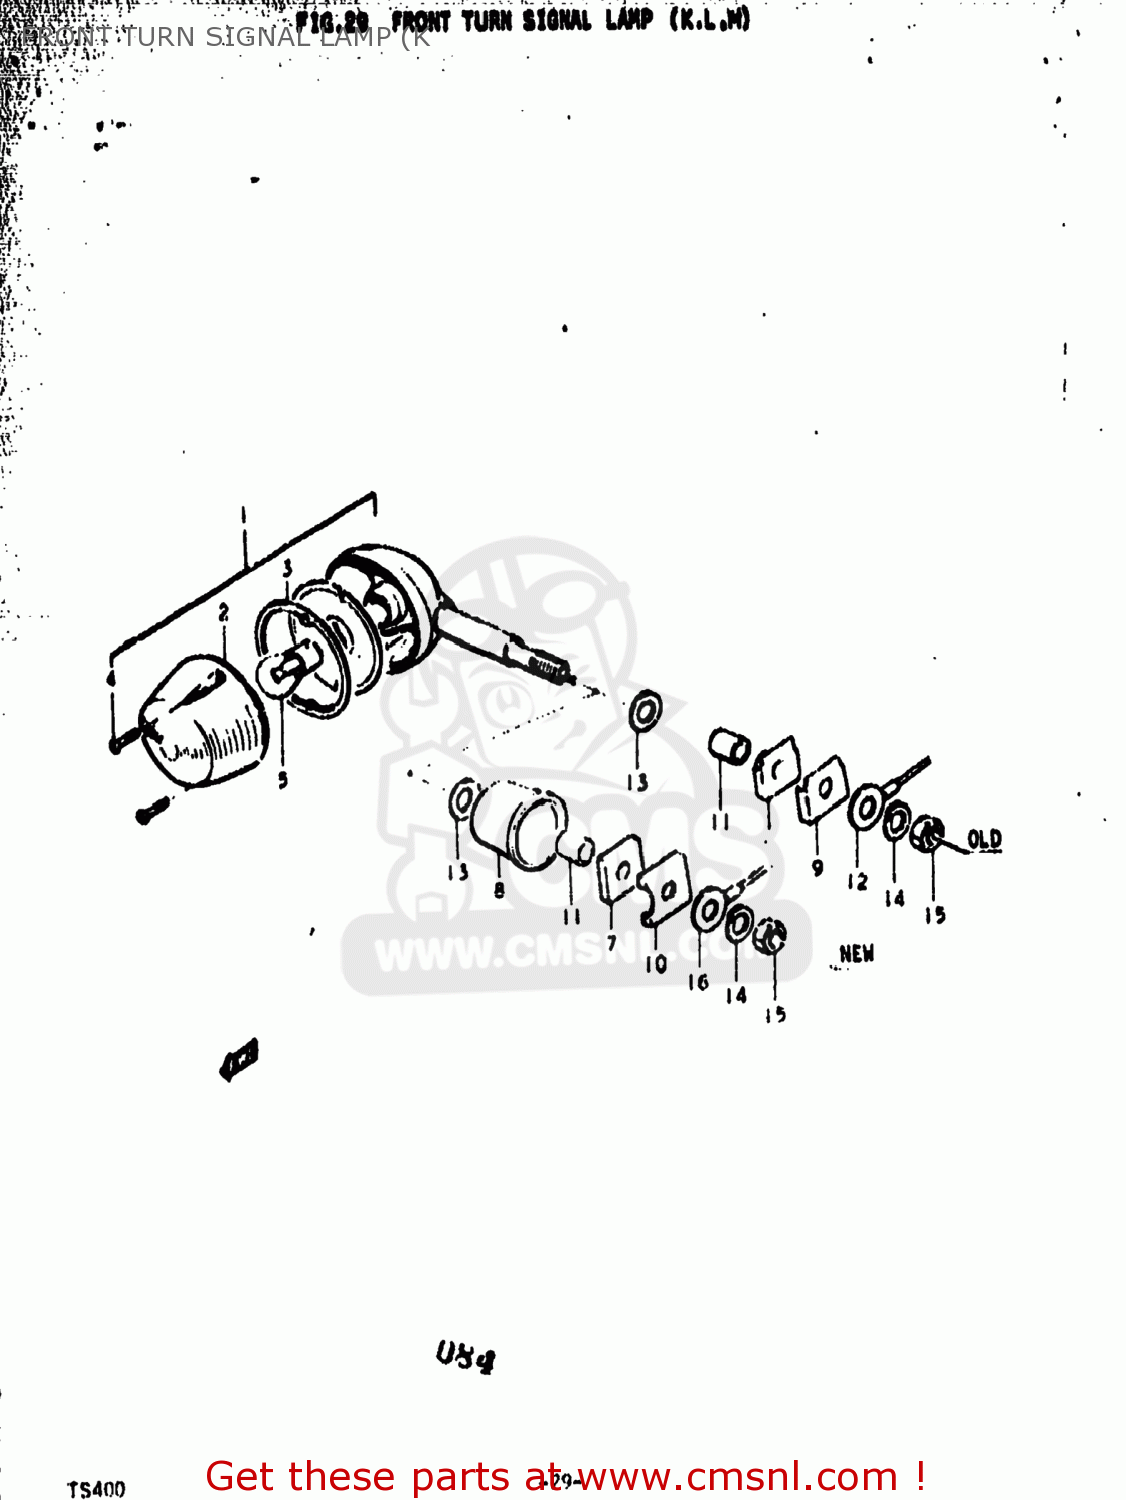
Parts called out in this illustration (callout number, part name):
1	LAMP ASSEMBLY,FRONT TURN SIGNAL
2	LENS,TURNSIGNAL
3	GASKET,TURNSIGNAL LENS (NAS)
4	SCREW
5	BULB(12V23W,STANLEY,A4577A)
6	CUSHION,FRONT TURNSIGNAL
7	CUSHION,FRONT TURNSIGNAL
8	CUSHION
9	PLATE, TURN SIGNAL
10	PLATE, TURN SIGNAL
11	SPACER, TURN SIGNAL
12	LEAD WIRE,EARTH
13	WASHER (10.5X30X2.3)
14	LOCK WASHER
15	NUT
16	LEAD WIRE,EARTH
